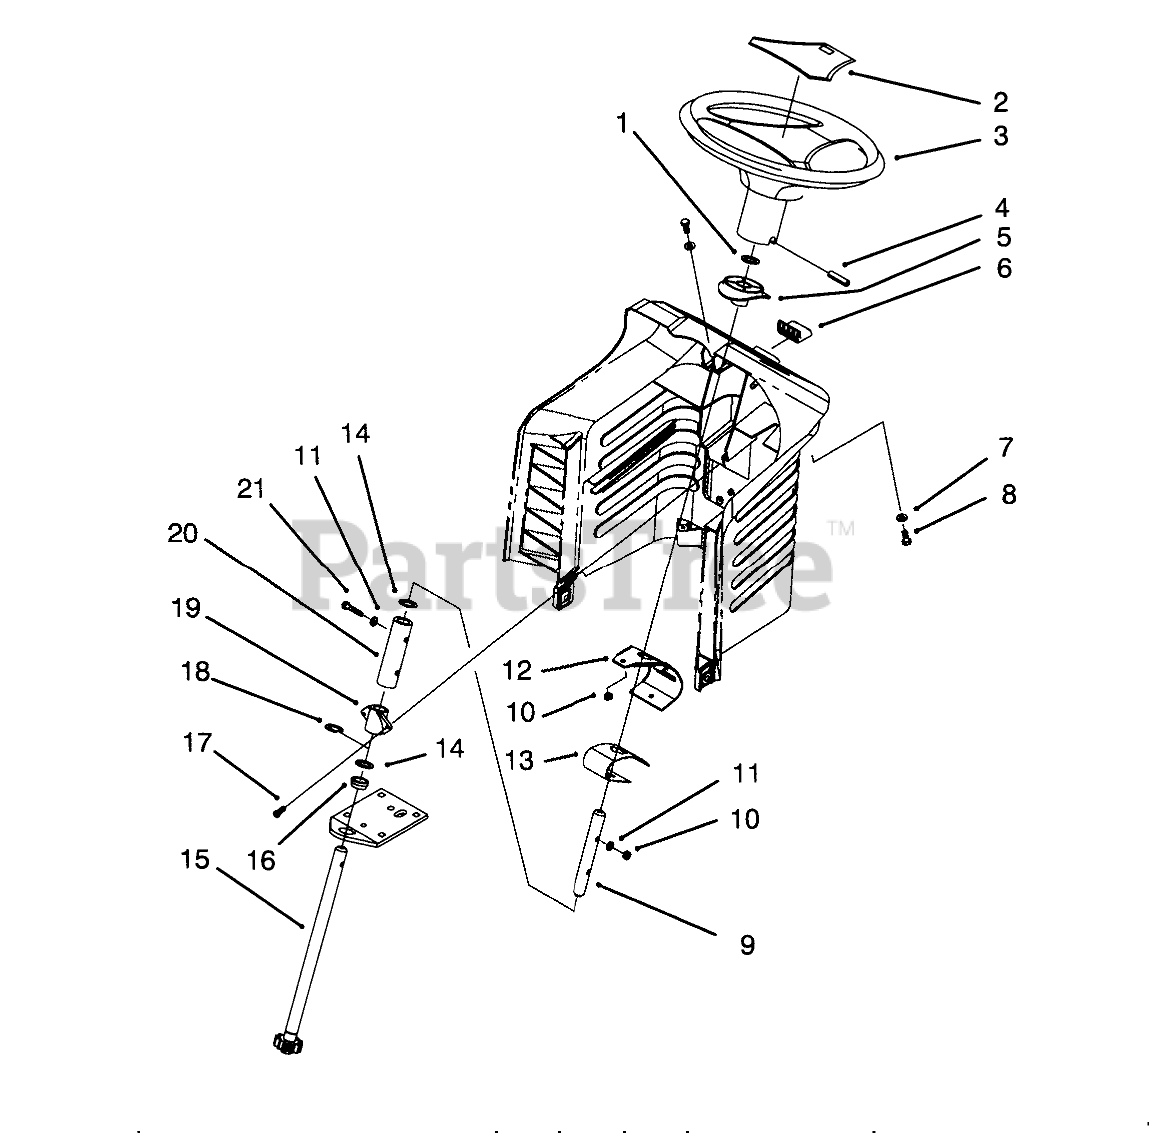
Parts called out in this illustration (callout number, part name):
1	PUSH-ON RETAINING RING
2	COVER-WHEEL
3	Wheel-Steering (Incl. Ref. #2)
4	PIN-ROLL
5	BUSHING-SLIDING
6	RELEASE BUTTON
7	WASHER-FLAT
8	SCREW-HH
9	UPPER STEERING SHAFT
10	NUT-LOCK, NI
11	WASHER
12	BACKUP BRACKET
13	SPRING LEAF
14	WASHER-THRUST
15	SHORT STRG SHAFT WA
16	BEARING-FLANGE
17	SCREW-SPECIAL
18	E-RING
19	BUSHING STATIONARY
20	COUPLING, STEERING
21	SCREW-HH
